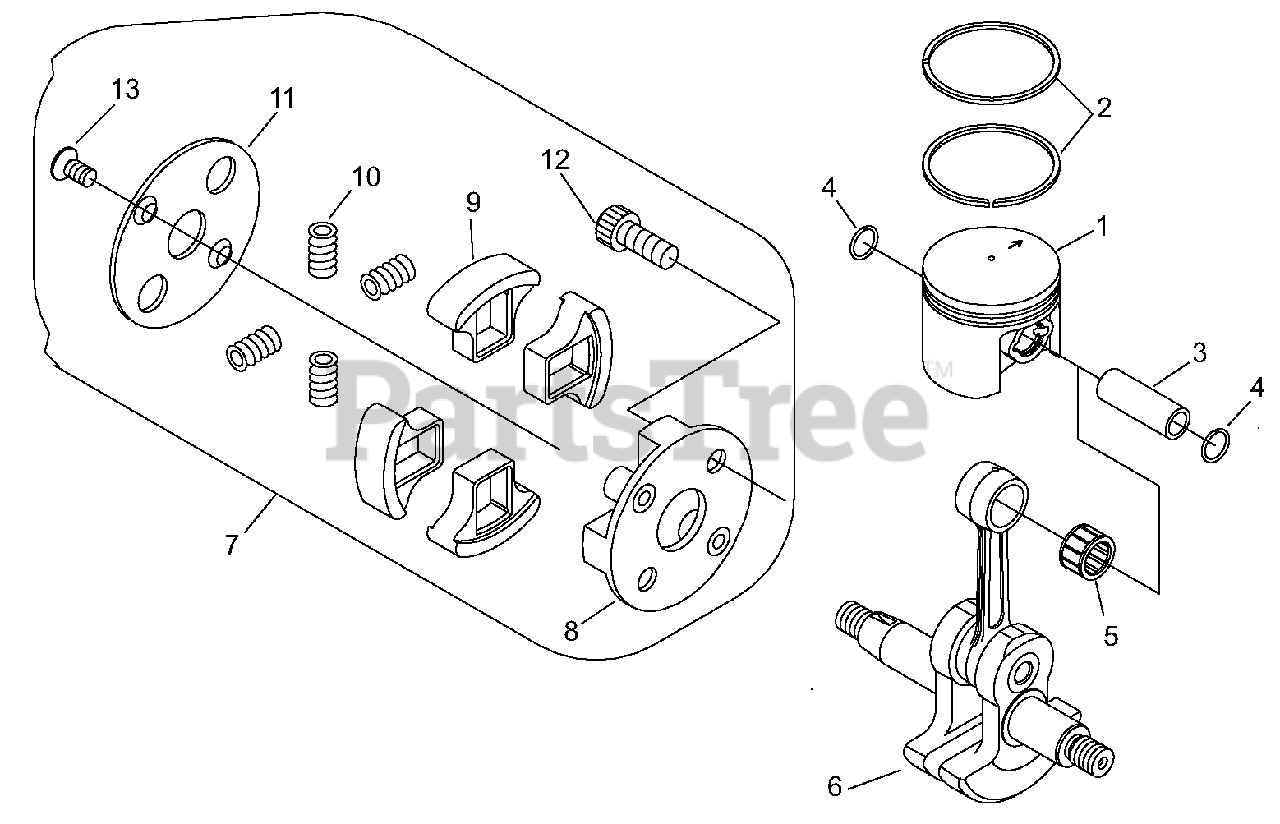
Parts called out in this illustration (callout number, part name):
1	PISTON
2	RING, PISTON
3	PIN, PISTON
4	RING, SNAP
5	BEARING, NEEDLE
6	CRANKSHAFT
7	CLUTCH ASSY
8	BOSS, CLUTCH
9	SHOE, CLUTCH
10	SPRING, CLUTCH
11	PLATE, CLUTCH
12	BOLT, CLUTCH
13	BOLT 5
